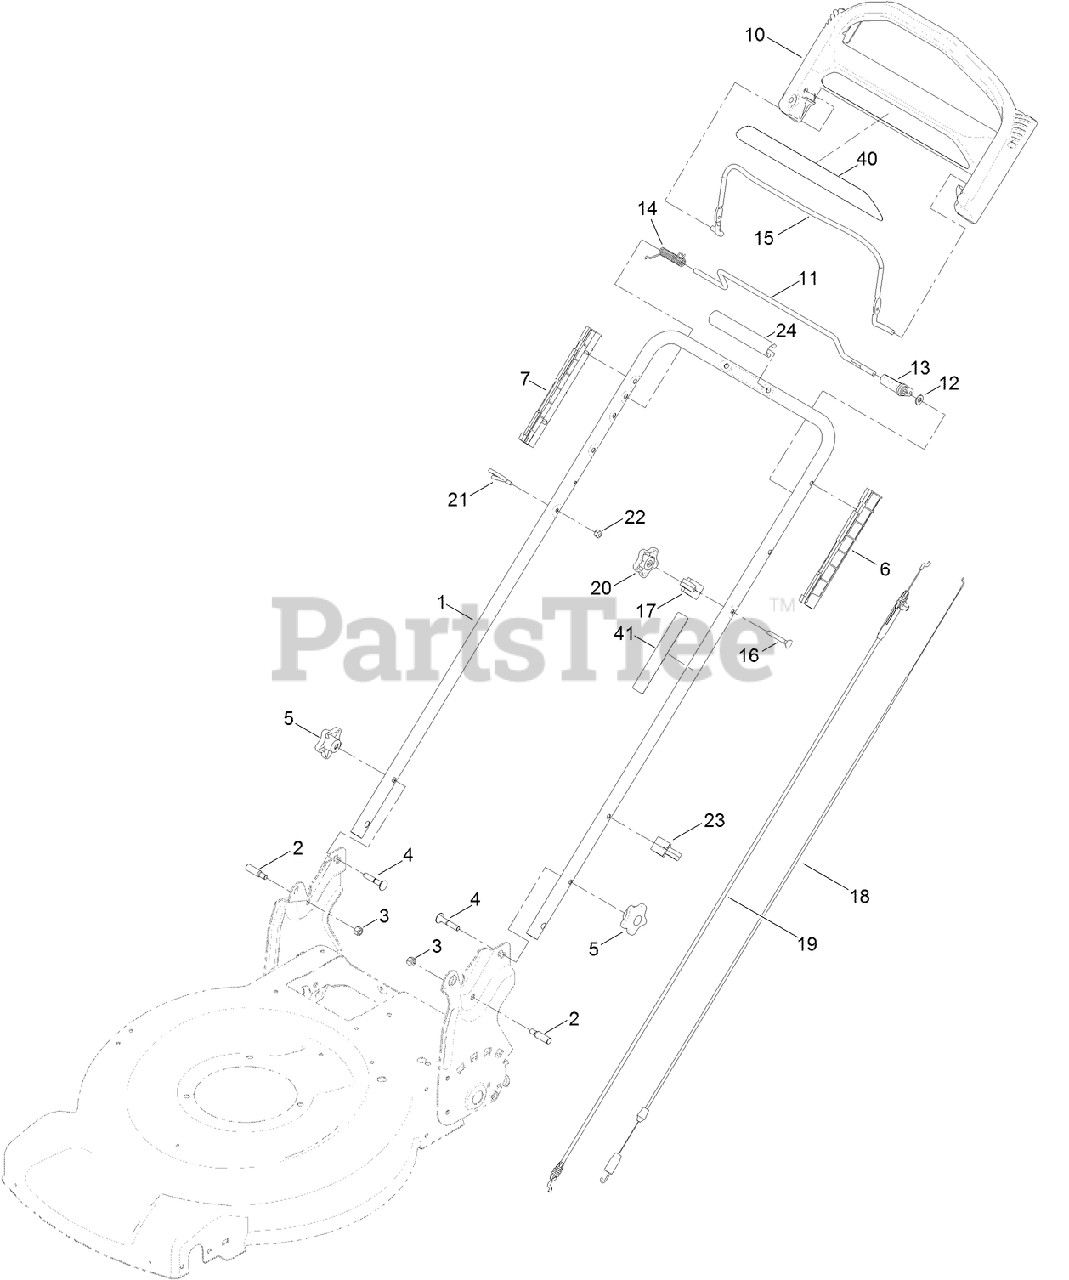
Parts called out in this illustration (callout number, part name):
2	BOLT-SHOULDER
3	NUT-LOCK, NI
4	SCREW-CARR
5	KNOB-HANDLE
6	GUIDE-LH
7	GUIDE-RH
10	HANDLE-CONTROL
11	BAR-CONTROL, TRACTION
12	WASHER-PLAIN
13	LEVER-TRACTION
14	Spring-Torsion
15	BAIL-BRAKE
16	SCREW
17	ANCHOR-CABLE
18	CABLE-TRACTION
19	CABLE-BRAKE
20	KNOB-HANDLE, LOCKING
21	GUIDE-ROPE
22	NUT-LOCK, NI
23	GUIDE-CABLE
24	HANDLE-COVER
40	DECAL-HANDLE
41	DECAL-TRACTION, ADJUST
